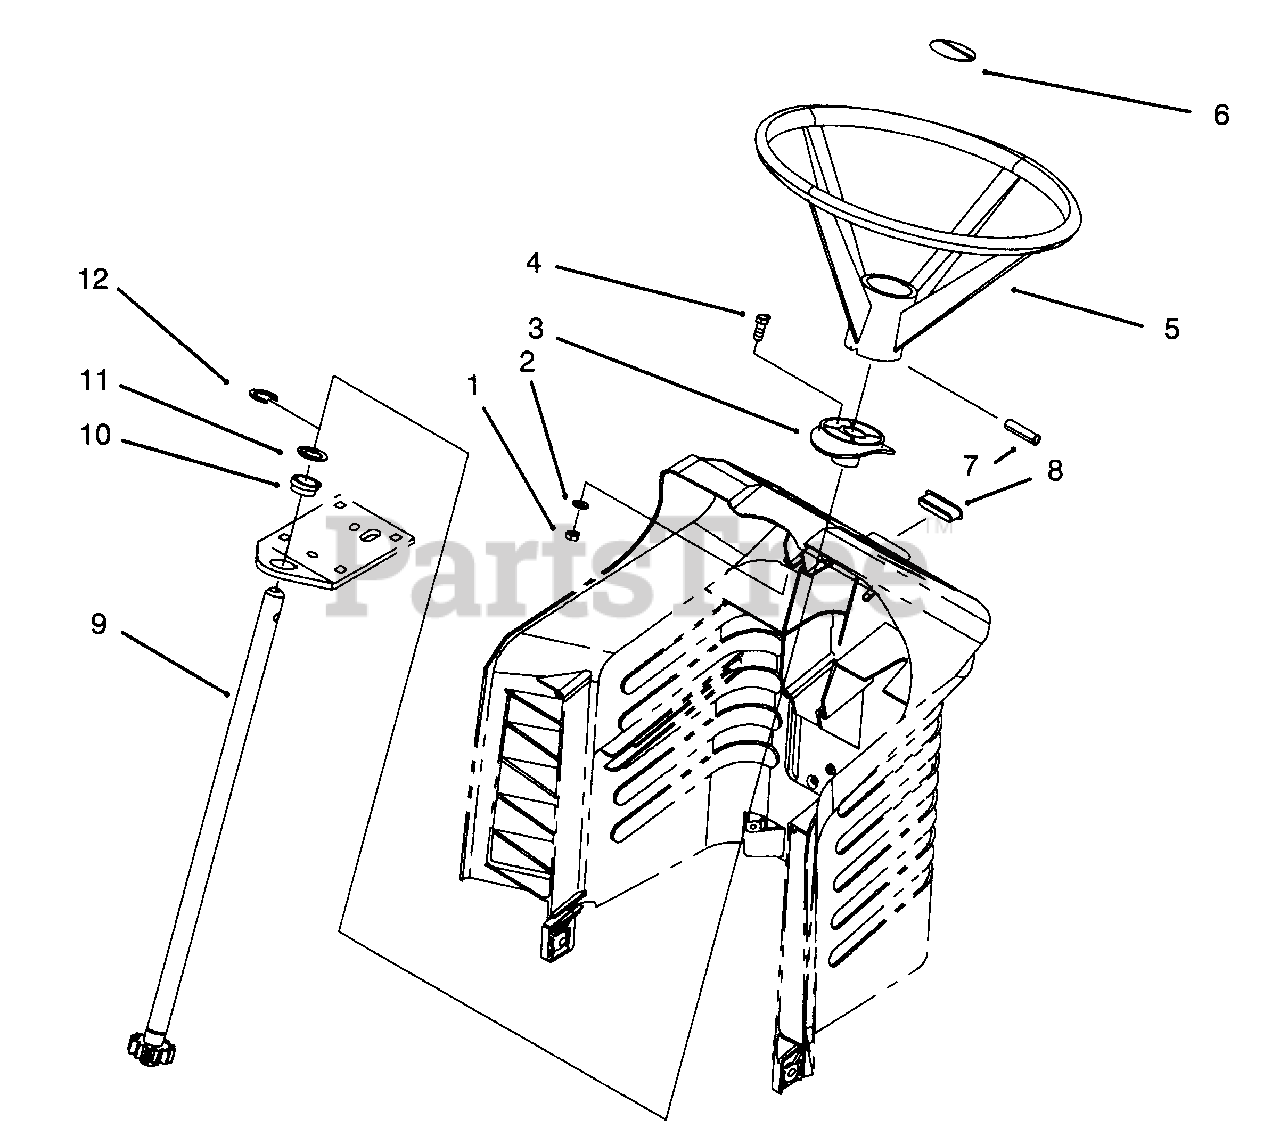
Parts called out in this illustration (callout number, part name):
1	Nut-Lock
2	Washer-Flat
3	Bushing-Sliding
4	Screw-Hex Hd. Cap
5	Wheel-Steering (Incl. Ref. #6)
6	Insert-Steering Wheel
9	Shaft-Steering
10	Bushing-Flange
11	Washer-Thrust
